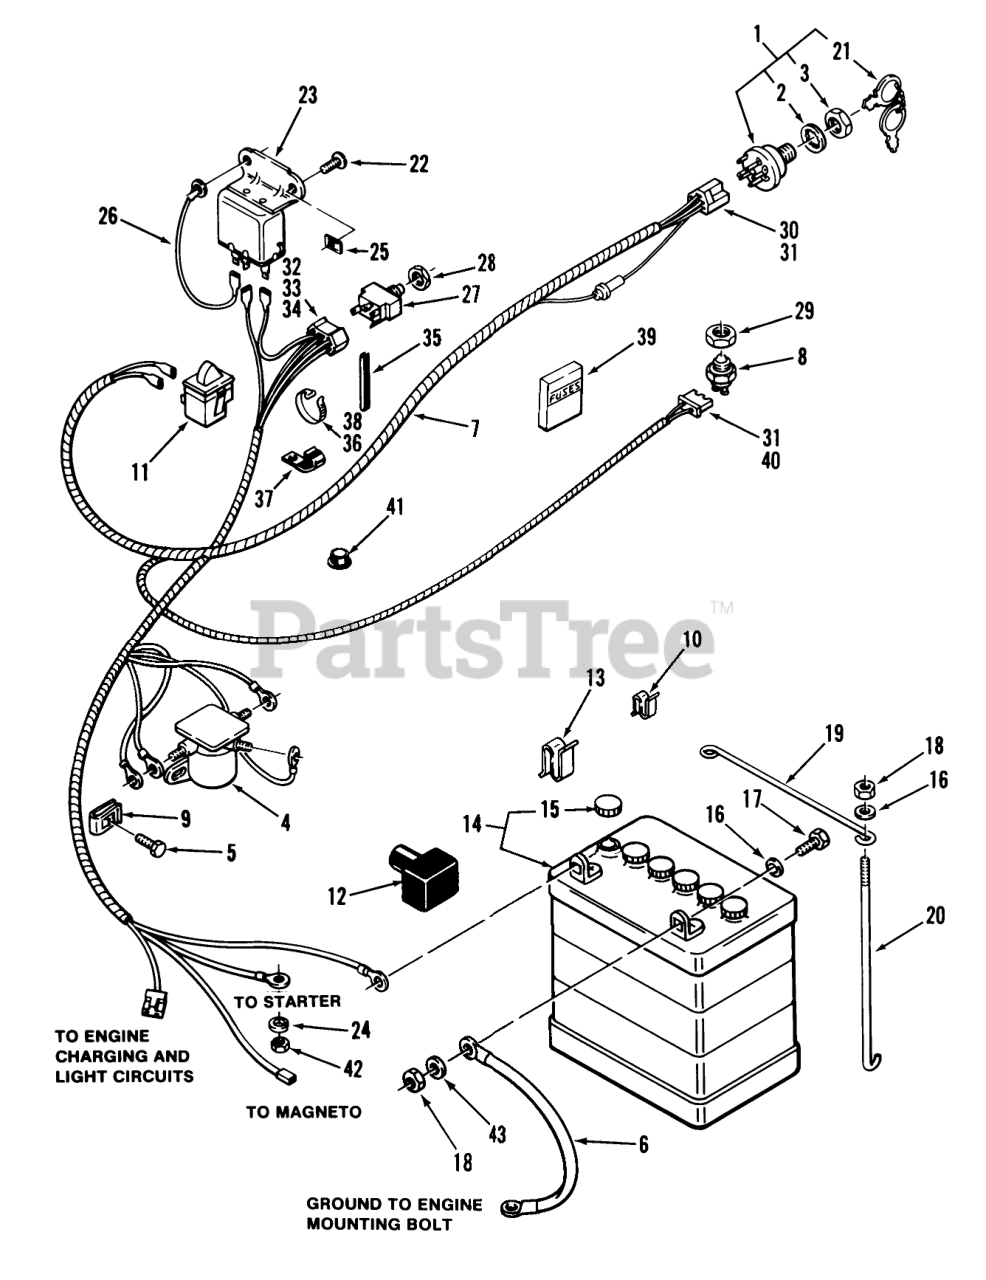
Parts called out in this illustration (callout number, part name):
1	SWITCH-IGNITION
2	LOCKWASHER
4	SOLENOID
5	HEX WASHER HD SCREW
6	Wire
7	Wiring Harness
8	SWITCH-INTERLOK CLUT
9	Speed Nut
10	SPEED CLIP
10	CLIP-CABLE
11	SWITCH INTERLOCK
12	Boot
13	Clip
14	Battery
17	Bolt
18	Nut
19	ROD-HOLD DOWN
21	Key-EL
22	Screw 10-24 X 5/8
23	Relay
24	Washer
25	Speed Nut
26	RELAY-GROUND WIRE
27	SWITCH-CLUTCH
28	NUT-HEX
29	NUT-SPECIAL 9/16-18
30	CONNECTOR-5 WAY-SERV
31	Terminal
32	CONNECTOR 5 WAY
33	TERMINAL-TAB RCPT
34	Terminal
35	EDGE TRIM 4IN OF 102896
36	Cable Tie
37	CLIP
38	PLASTIC TIE
40	CONNECTOR BODY
41	BUSHING-NYLON .75
42	Nut
43	Washer
